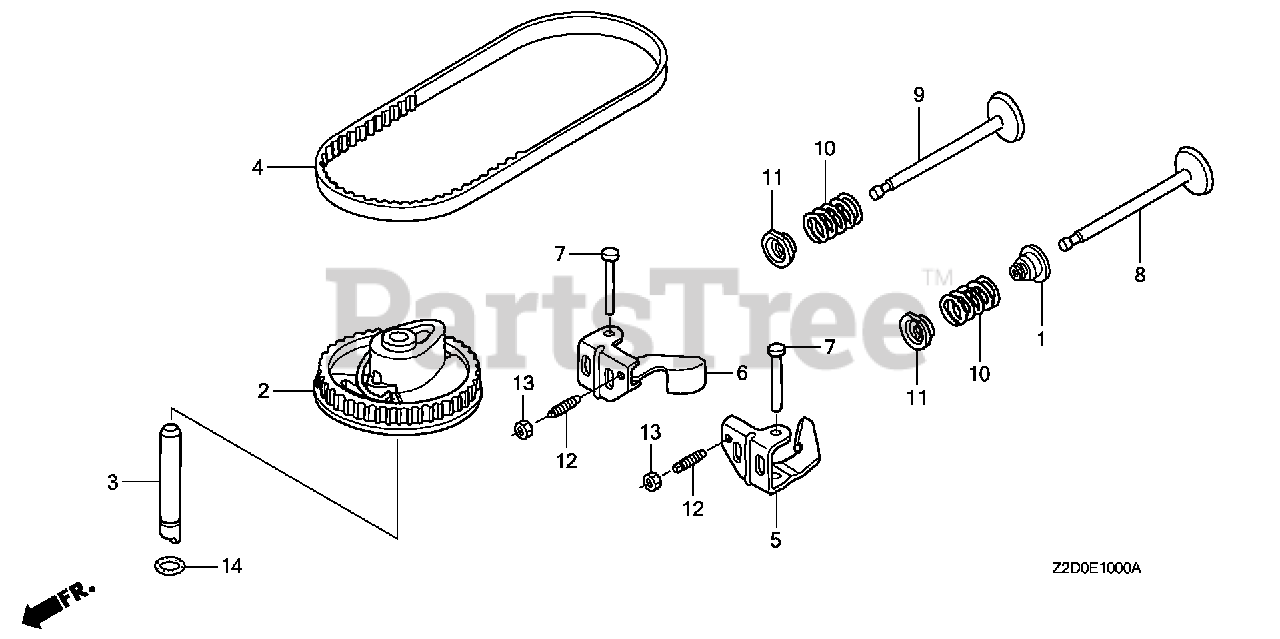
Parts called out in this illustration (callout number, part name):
1	SEAL, VALVE STEM
2	PULLEY, CAMSHAFT
3	SHAFT, CAM PULLEY
4	BELT, TIMING (84HU7 G-200)
4	BELT, TIMING (84HU6 G-200)
5	ARM, IN. VALVE ROCKER
6	ARM, EX. VALVE ROCKER
7	SHAFT, ROCKER ARM
8	VALVE, IN. (TECHNOSTAR)
8	VALVE, IN. (ROCKNEL)
8	VALVE, IN.
9	VALVE, EX. (L8E)
9	VALVE, EX. (C8E)
10	SPRING, VALVE
11	RETAINER, IN. VALVE SPRING
11	RETAINER, VALVE SPRING
12	SCREW, TAPPET ADJUSTING
13	NUT, TAPPET ADJUSTING
14	O-RING (6.8X1.9) (ARAI)
